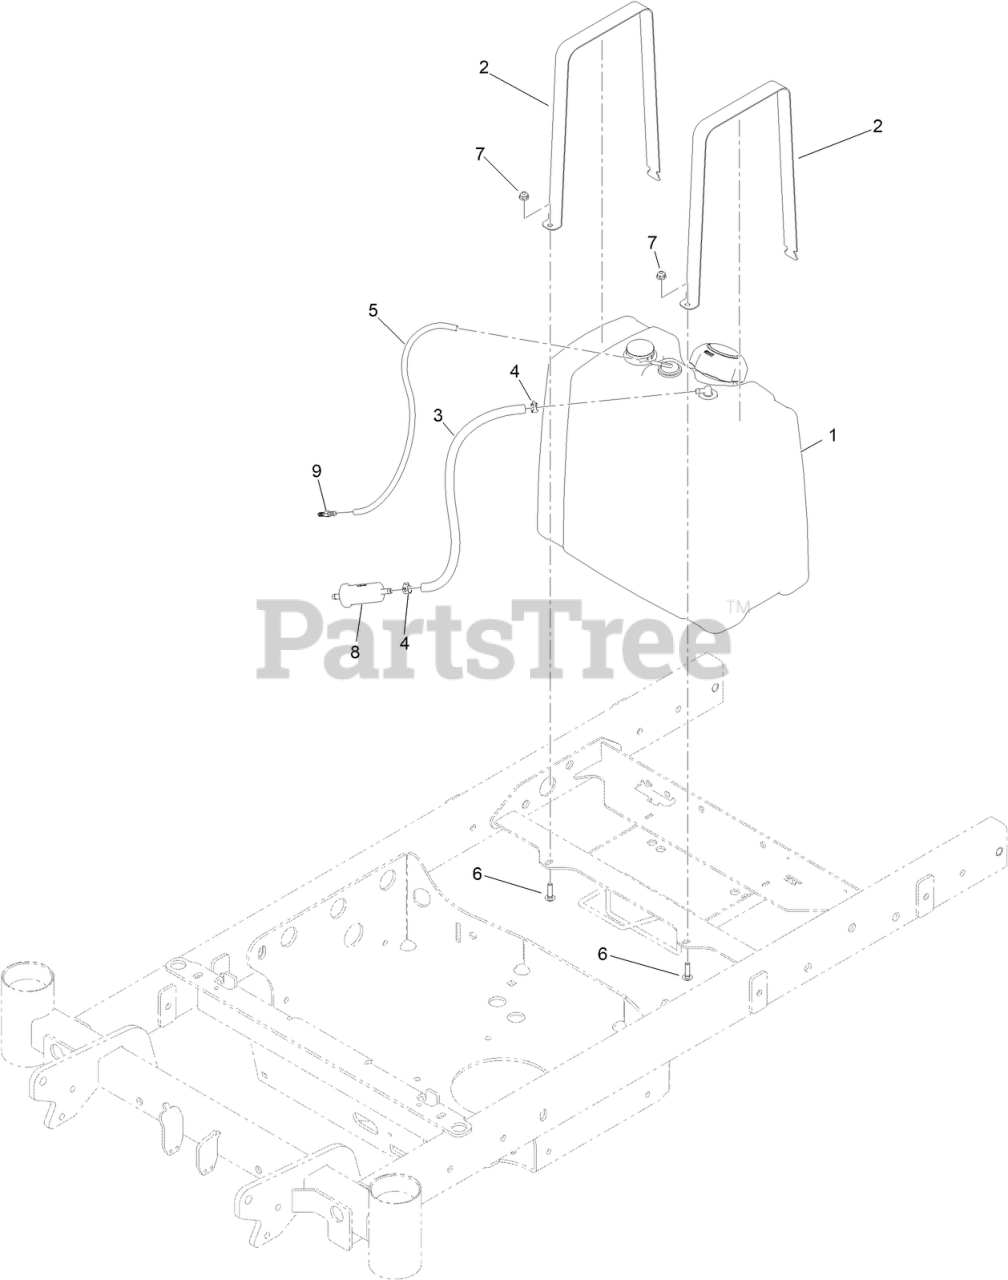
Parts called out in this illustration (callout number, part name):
1	ASM-TANK, FUEL
2	STRAP-TANK
3	HOSE-FUEL
4	CLAMP-HOSE
5	HOSE-FUEL
6	SCREW-CARR
7	Nut-Hex Flange
8	FILTER-FUEL
9	Fitting-STR
